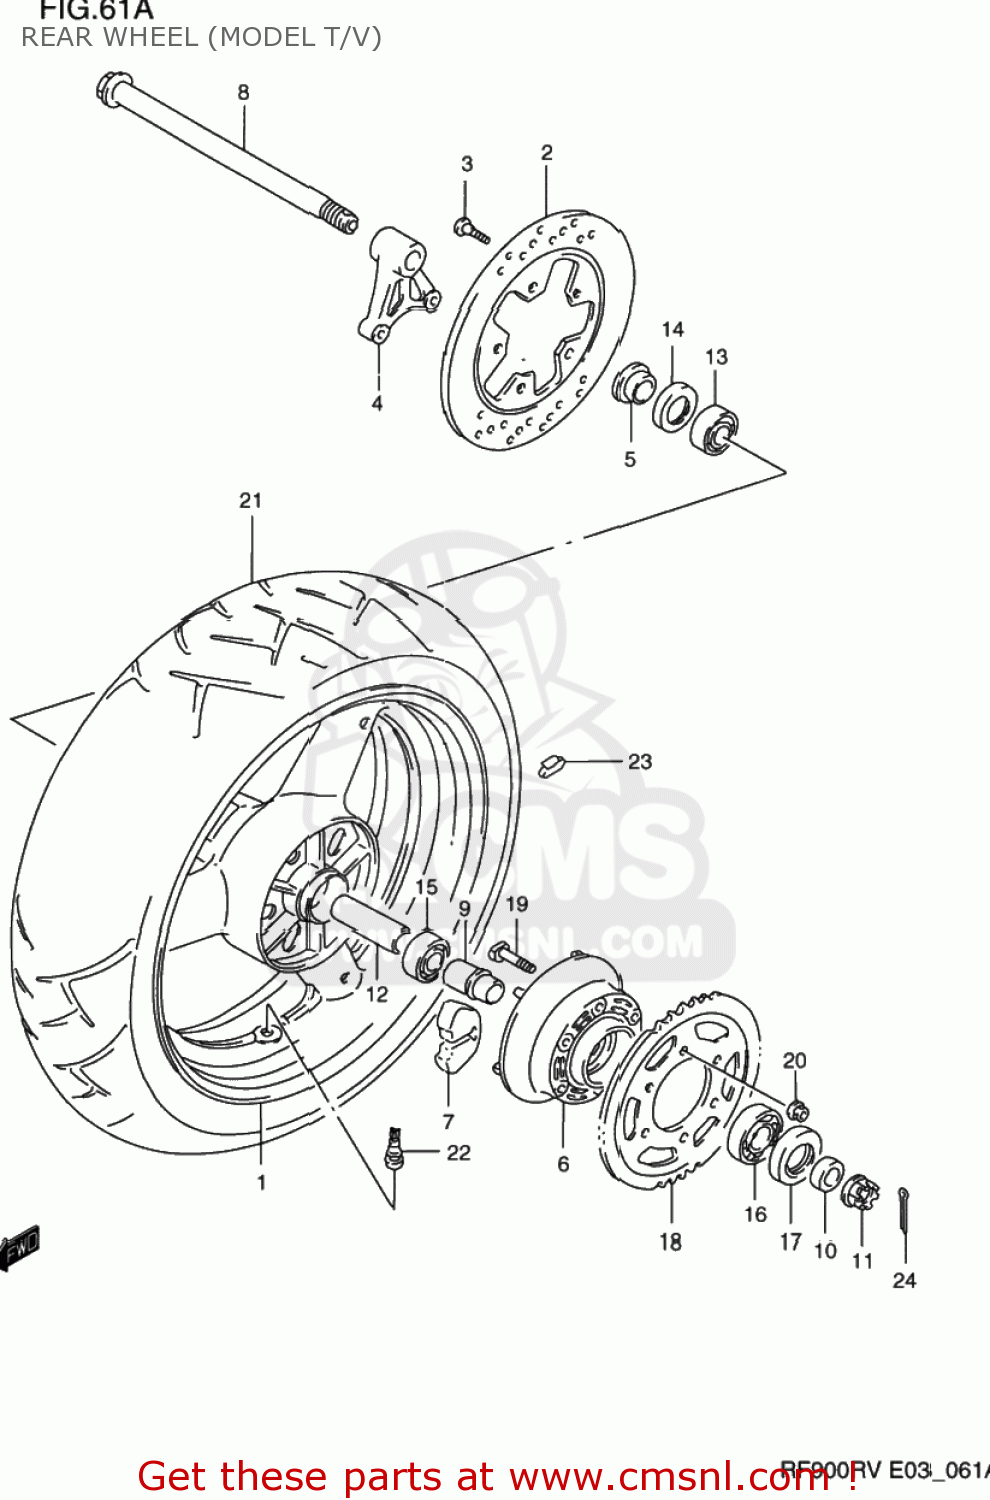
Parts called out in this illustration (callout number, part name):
1	WHEEL,REAR (MT5.50X17)(S
2	DISC,RR BRAKE
3	BOLT 8X33
4	BRACKET,RR CALIPER
5	SPACER,RR AXLE,R
6	DRUM,RR SPROCKET
7	ABSORBER,RR HUB SHOCK
8	AXLE,RR
9	RETAINER,RR HUB BEARING
10	SPACER,RR AXLE,L
11	NUT
12	SPACER,RR WHEEL HUB BEARING
13	BEARING(20X47X14)
14	SEAL,OIL(28X47X7)
15	BEARING(20X47X14)
16	BEARING(25X62X17)
17	SEAL,OIL(35X62X8)
18	SPROCKET,RR(NT:43)
19	BOLT
20	NUT
21	TIRE,REAR 170/60 ZR17
22	VALVE ASSEMBLY,WHEEL,TR412
23	BALANCER,WHEEL (10G)
24	PIN, COTTER
